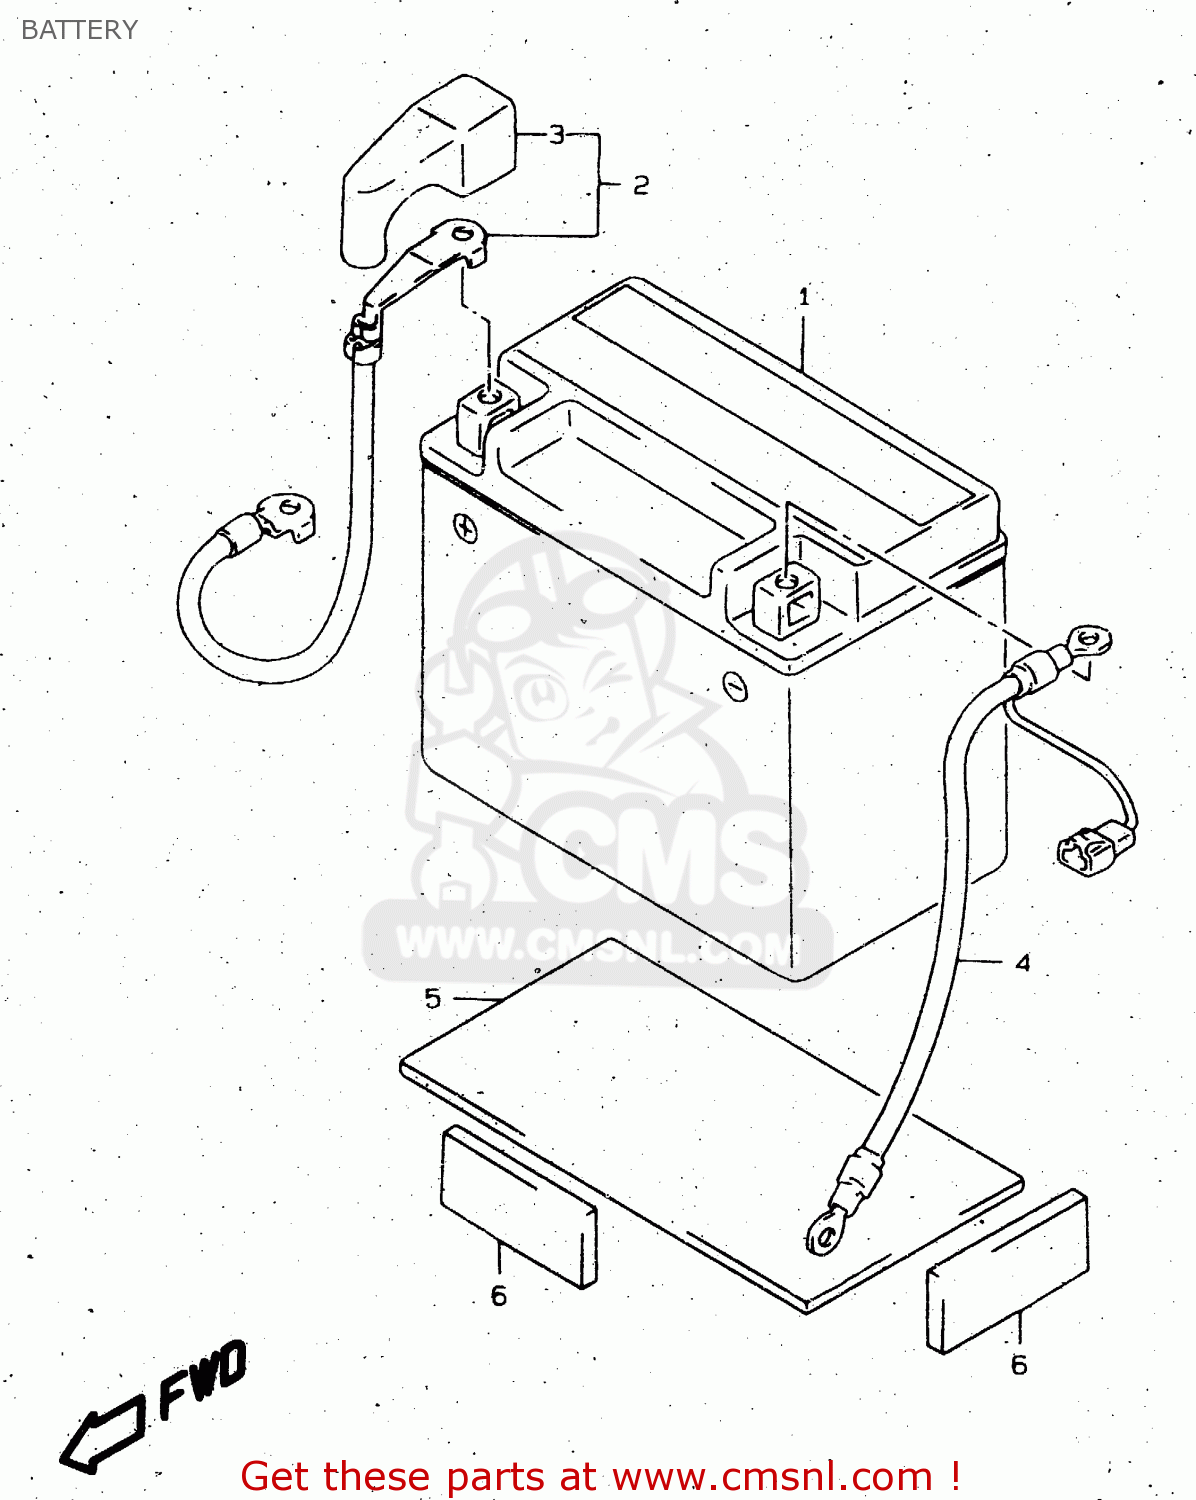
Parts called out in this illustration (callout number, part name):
1	BATTERY ASSY(YTX9-BS,12V8AH)
2	WIRE,BATTERY PLUS
3	CAP,BATTERY PLUS TERMINAL
4	WIRE,BATTERY MINUS
5	PROTECTOR(170X95X3.0)
6	CUSHION 20X45X6
